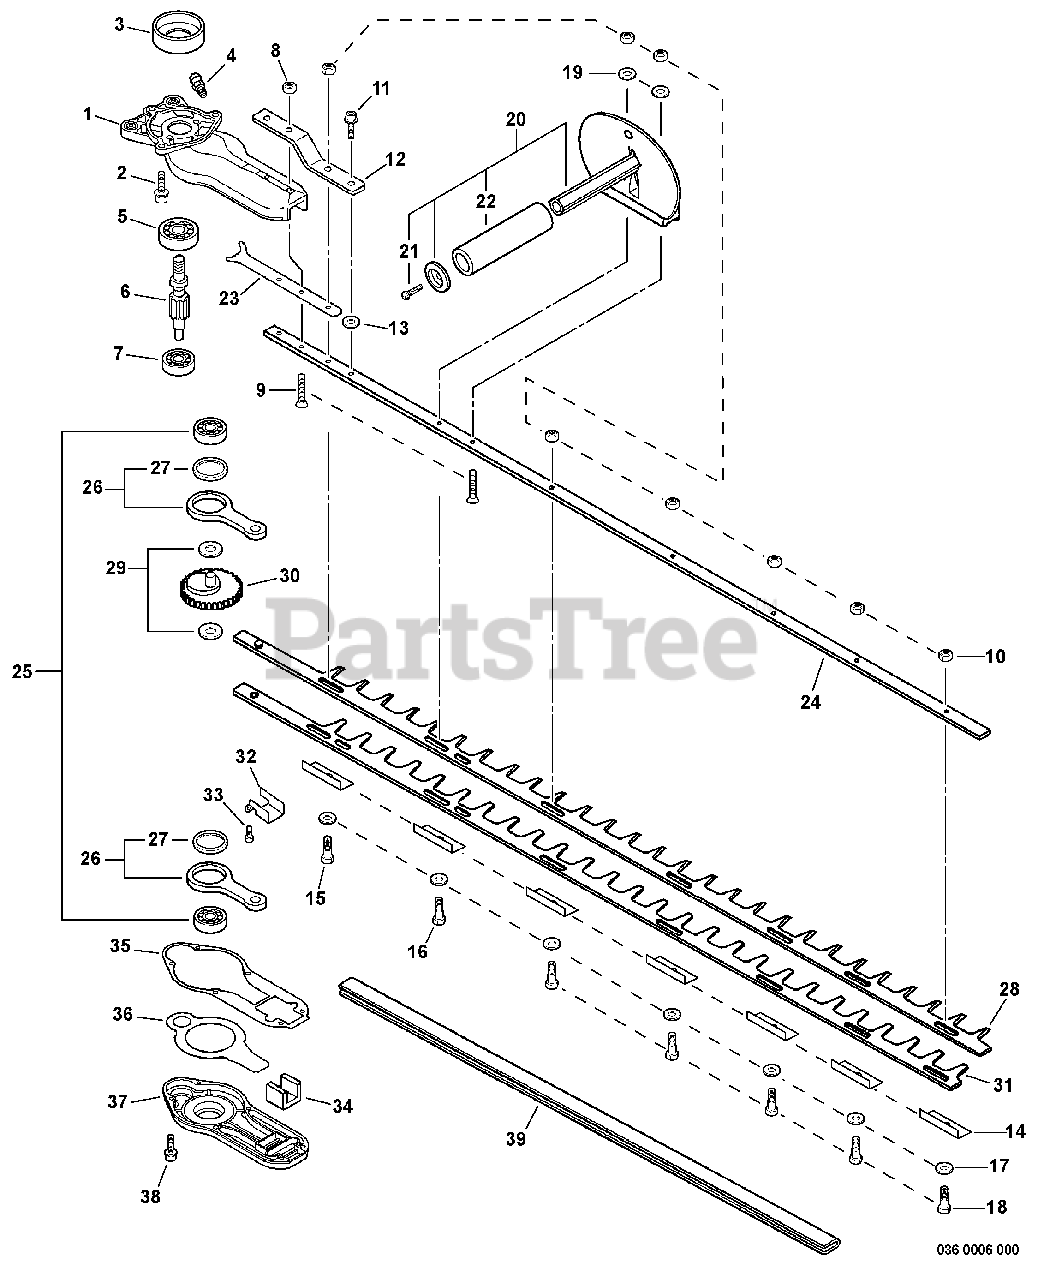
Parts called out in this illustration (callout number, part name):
1	CASE, GEAR - UPPER
2	SCREW - 6X18
3	DRUM, CLUTCH
4	FITTING, GREASE
5	BEARING, BALL - 6200
6	GEAR - SPUR
7	BEARING, BALL - 608ZZ
8	NUT - 6 -- FLANGE
9	SCREW - 6X30
10	LOCKNUT - 6
11	SCREW - 6X12
12	BRACKET, ANGLE
13	WASHER - 6
14	INSULATOR
15	BOLT - 6X35
19	WASHER - 6
20	HANDLE ASSY - FRONT
21	SCREW - 5X14
22	GRIP, HANDLE
24	SUPPORT, BLADE - 40" (101cm)
25	BEARING, BALL - 6200
26	ROD, CONNECTING
27	BEARING, NEEDLE
28	BLADE - 40" (101cm) -- UPPER
29	WASHER - 10
30	GEAR - SPUR
31	BLADE - 40" (101cm) -- LOWER
32	GUIDE, BLADE
33	SCREW - 4X16
35	GASKET, GEAR CASE
36	PLATE, GEAR CASE
37	CASE, GEAR - LOWER
38	SCREW - 4X16
39	COVER, BLADE
